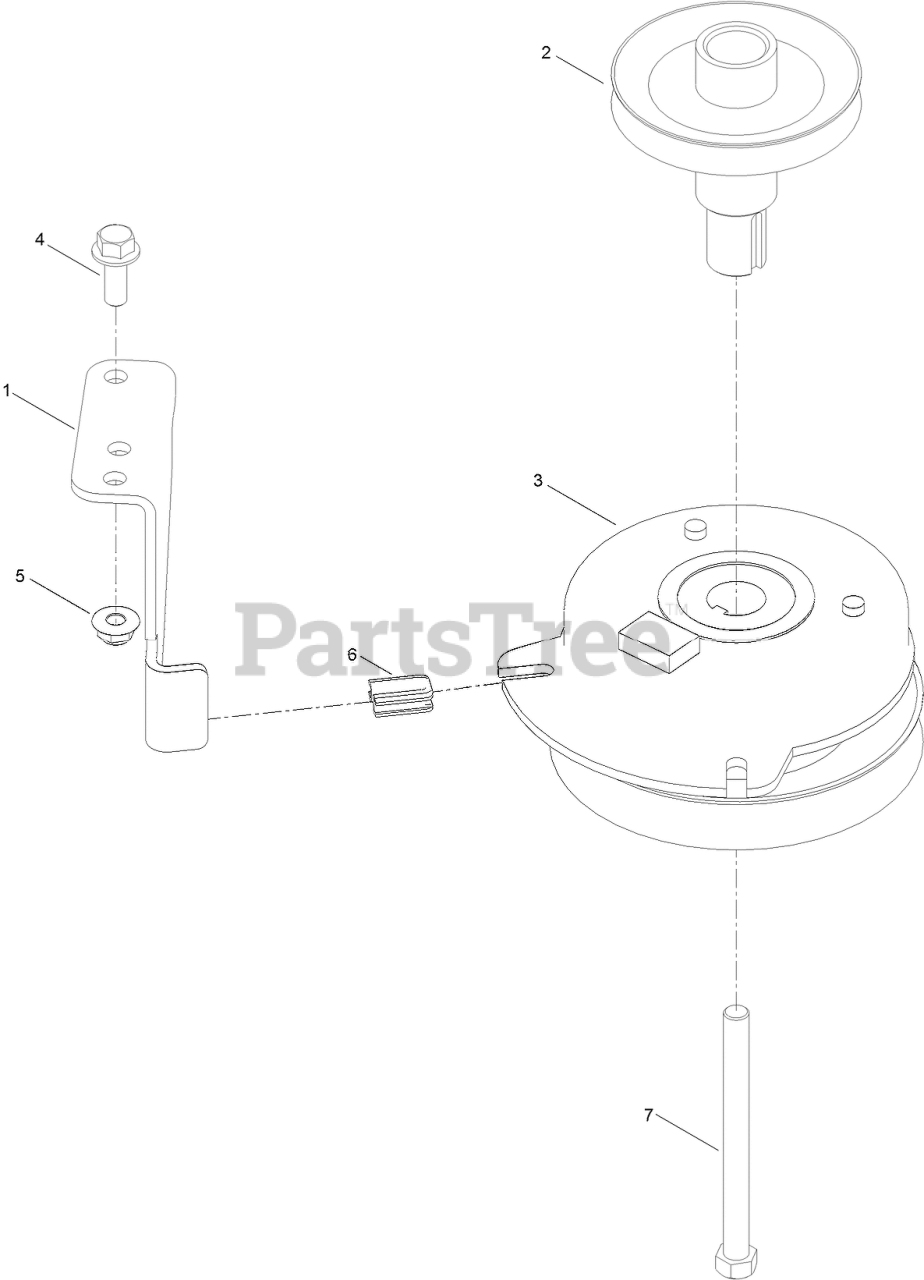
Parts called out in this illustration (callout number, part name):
1	STOP-CLUTCH (WIDE)
2	PULLEY-ENGINE
3	CLUTCH-PTO
4	SCREW-HHF
5	NUT-HF, NI
6	ISOLATOR-CLUTCH
7	SCREW-HH
